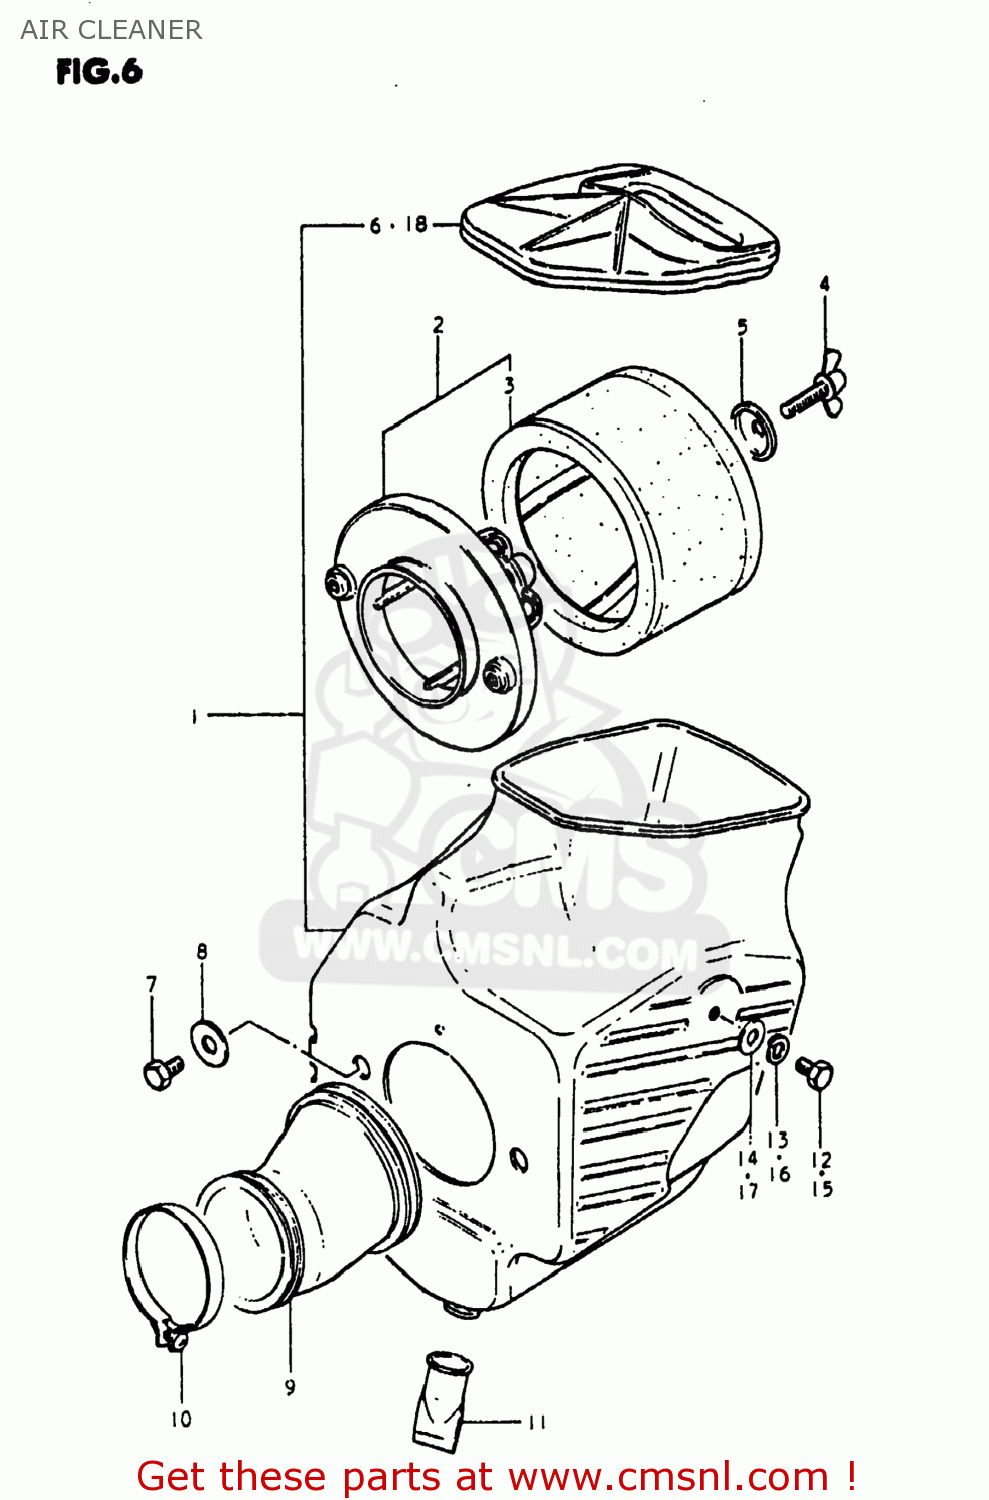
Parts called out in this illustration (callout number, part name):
1	CLEANER ASSEMBLY,AIR
2	FILTER,AIR CLEANER
3	FILTER
4	WING BOLT,AIR CLEANER
5	HOLDER,FILTER
6	CAP,AIR CLEANER
7	BOLT
8	SPACER,AIR CLEANER,REAR
9	TUBE,AIR CLEANER OUTLET
10	CLAMP
11	HOSE, DRAIN
12	BOLT
13	LOCK WASHER
14	WASHER
15	BOLT
16	LOCK WASHER
17	WASHER
18	CAP,AIR CLEANER
